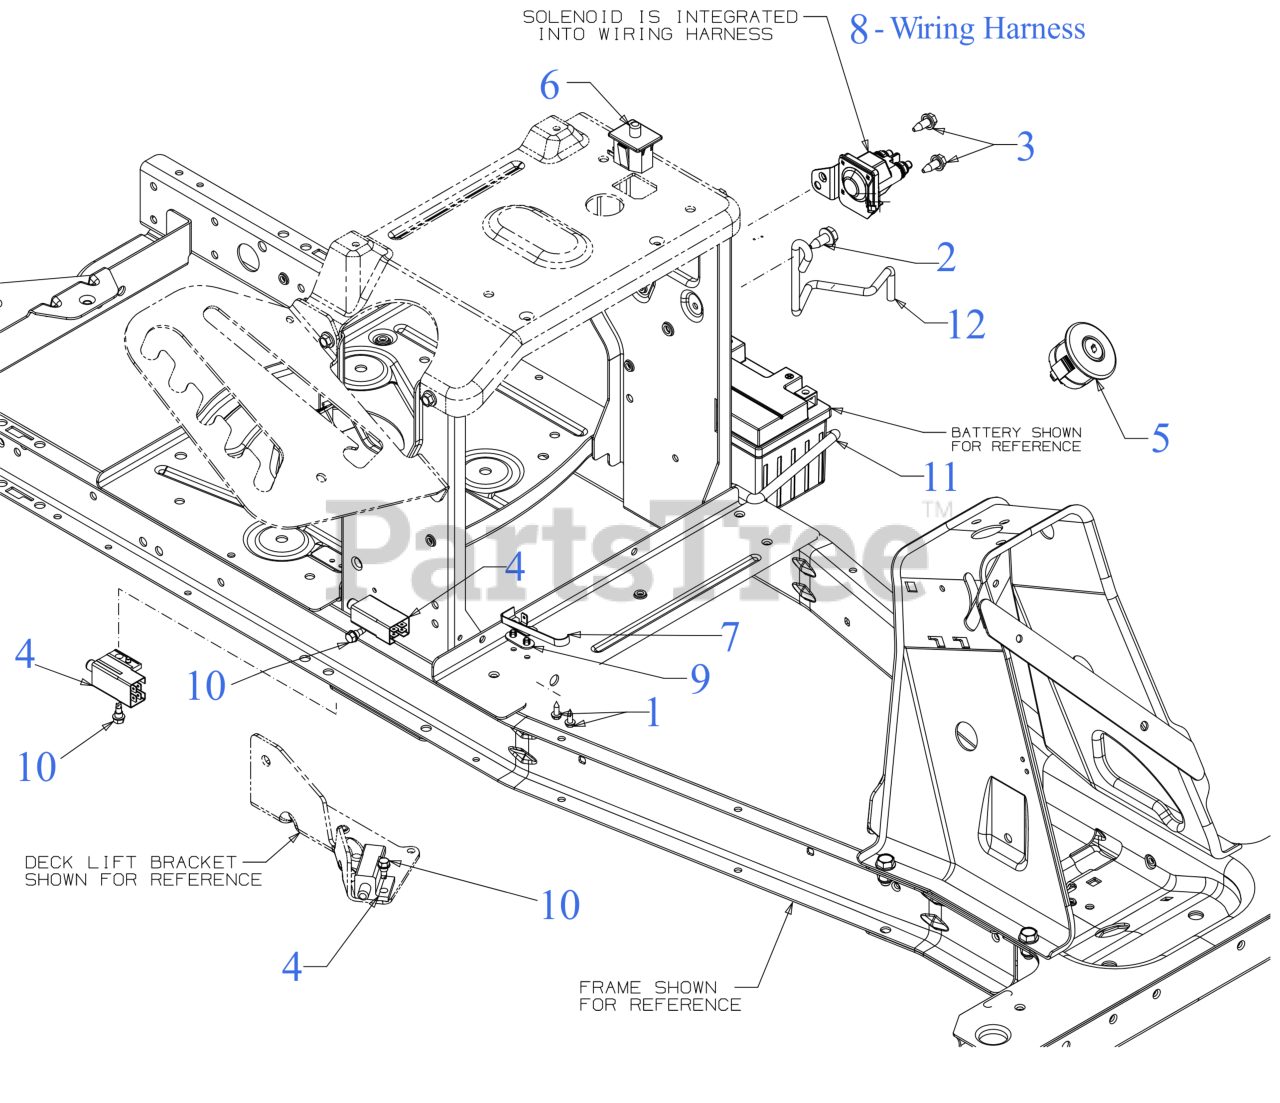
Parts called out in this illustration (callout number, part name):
1	HEX SCREW WASHER HD #8-18 x 0.500
2	SCREW 5/16-18 x .750
3	SCREW 1/4-20X.625
4	INTERLOCK SWITCH (NO/NC)
5	KEY SWITCH 3 POS WHITE PAD
6	SEAT SWITCH N/C,N/C
7	SPRING SWITCH
8	HARNESS (3POS SOL ACDC&DC AGM)
8	12V SOLENOID
9	INSULATOR NUT PLATE
10	SHOULDER SCREW
11	BATTERY TRAY ROD
12	BATTERY HOLD DOWN ROD
